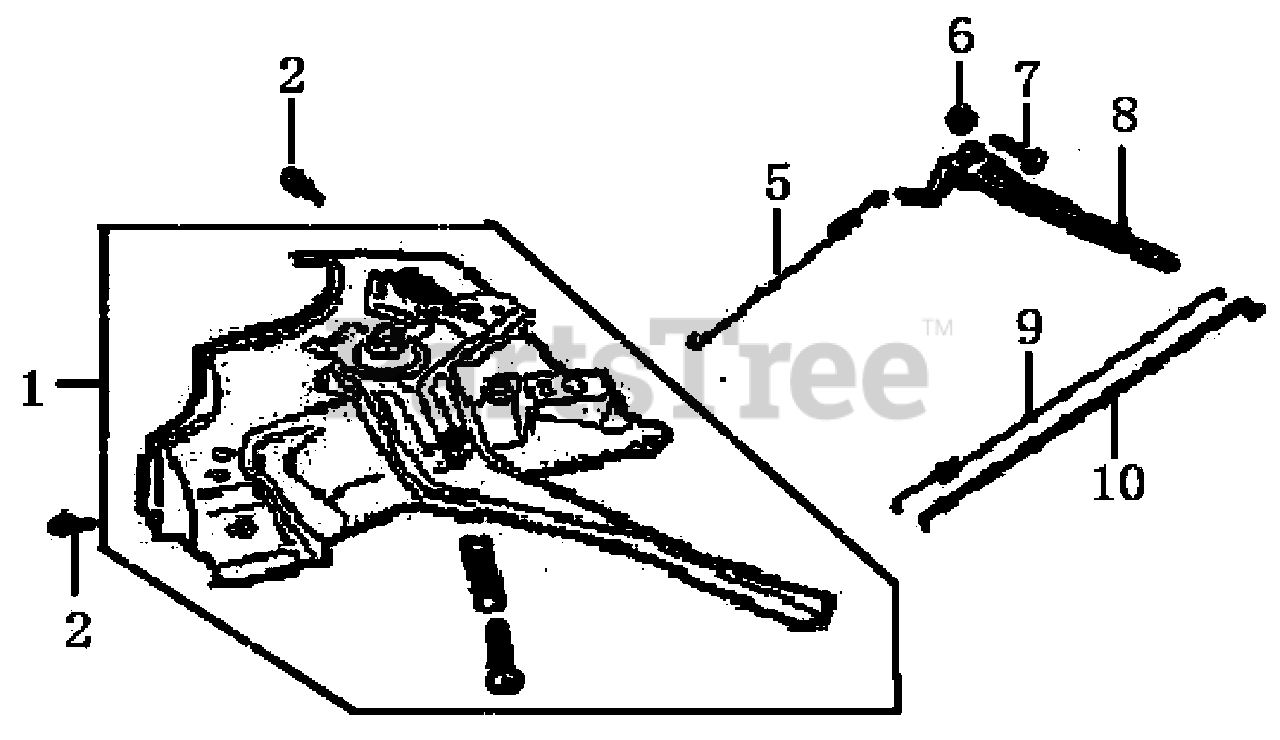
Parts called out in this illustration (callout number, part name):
1	CONTROL ASSY.
5	SPRING, CABLE RETURN
6	NUT, FLANGE
7	BOLT, QUADRATE HEAD
8	ARM, GOVERNOR
9	SPRING, THROTTLE RETURN
10	ROD, GOVERNOR
